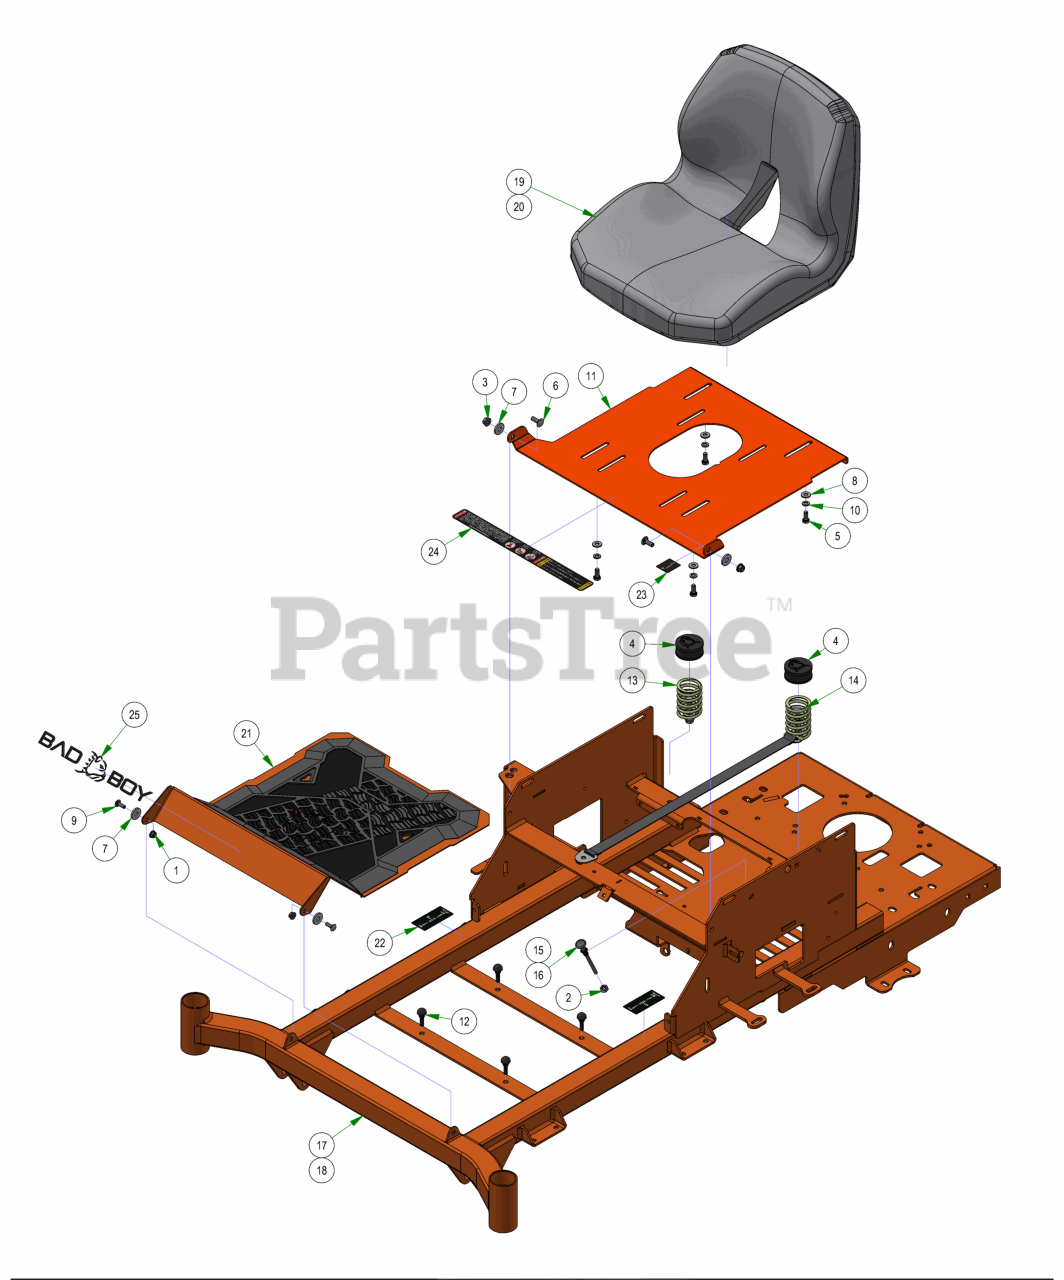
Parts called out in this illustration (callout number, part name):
1	1/4-20 NYL INSERT FLANGE LOCKNUT ZINC
2	3/8-24 HEX NUT ZINC YELLOW
3	5/16-18 NYLON INSERT FLANGE LOCKNUT ZINC
4	Spring Cap Cover
5	5/16-18 X 3/4 HEX CAP SCREW (GR.5) ZINC
6	5/16-18 X 7/8 CARRIAGE BOLT ZINC
7	.360 ID X .983 OD X .120 THICK FLAT WASHER NYLON
8	1/4 USS FLAT WASHER (3/4 OD) ZINC
9	1/4-20 X 3/4 CARRIAGE BOLT (GR.5) ZINC
10	5/16 SPLIT LOCKWASHER ZINC
11	2022 Avenger Seat Plate
12	2023 Floor Board Rubber Bumper
13	Seat Spring Assembly
14	2022 Mav/HD seat spring assembly with strap
15	Choke (42" Only)
17	2025 MZ 42-48 Frame
18	2025 MZ-Avenger 54-60 Frame
19	2025 Magnum & Rambler Seat
20	2022 Avenger Seat
21	2025 MZ/Avenger Floorboard Assembly
22	2018 LH/RH Steering Control Decal Roll
23	2018 MZ/Magnum/ZT/MAV/Comp Out Brake Decal
24	Outlaw Warning Decal
25	Flying Bulldog Front Bumper Decal
